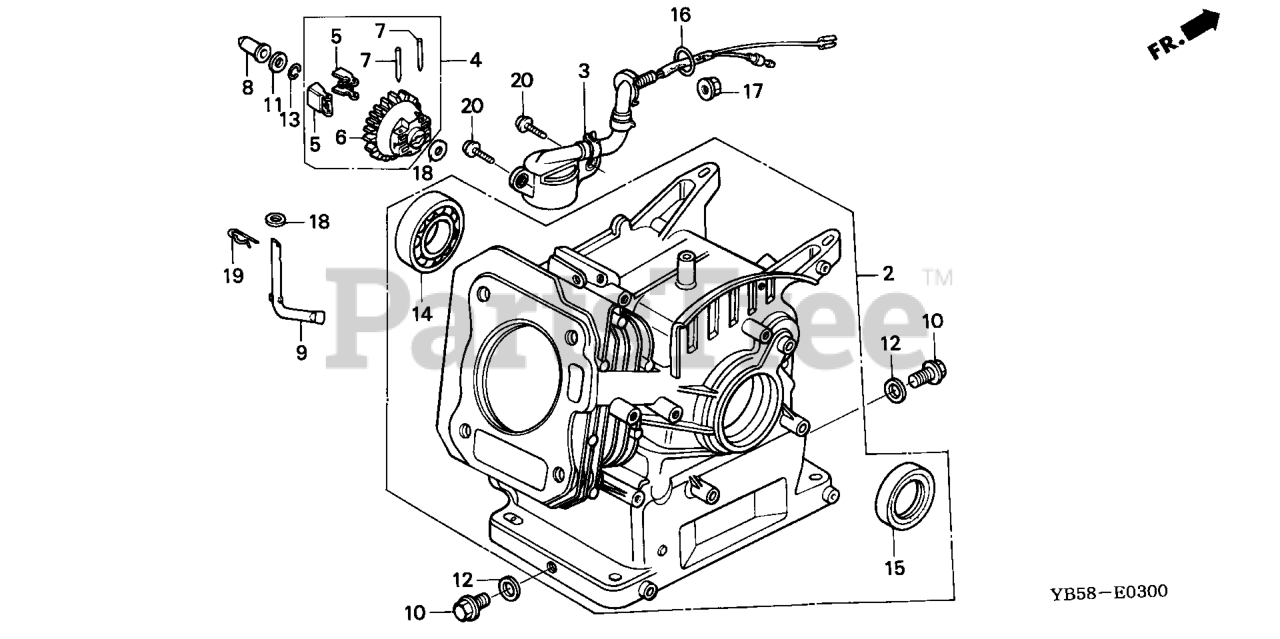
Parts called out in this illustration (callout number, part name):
2	CYLINDER ASSY.
4	GOVERNOR ASSY.
5	WEIGHT, GOVERNOR
6	HOLDER, GOVERNOR WEIGHT
7	PIN, GOVERNOR WEIGHT
8	SLIDER, GOVERNOR
9	SHAFT, GOVERNOR ARM
10	BOLT, DRAIN PLUG
11	WASHER, THRUST (6MM)
12	WASHER, DRAIN PLUG (10.2MM)
13	CLIP, GOVERNOR HOLDER
14	BEARING, RADIAL BALL (6205)
15	OIL SEAL (25X41X6)
18	WASHER, PLAIN (6MM)
19	PIN, LOCK (8MM)
